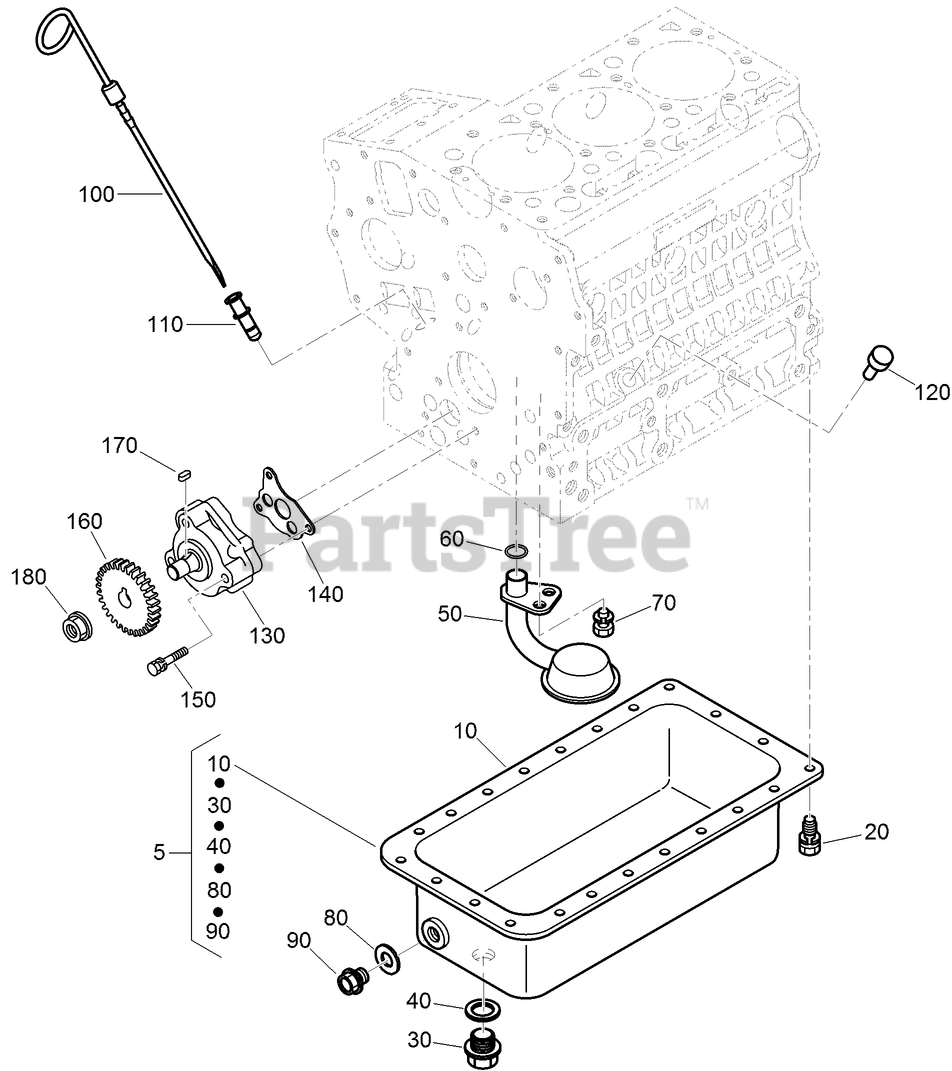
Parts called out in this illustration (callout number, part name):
5	OIL PAN KIT
10	PAN-OIL
30	PLUG-DRAIN
40	GASKET-PAN, OIL
50	STRAINER-PICKUP, OIL
60	O-RING
80	GASKET
90	PLUG-DRAIN
100	GAUGE-OIL
110	GUIDE-GAUGE, OIL
120	PLUG-GAUGE, OIL
130	OIL PUMP ASM
140	GASKET-PUMP, OIL
160	GEAR-DRIVE, OIL PUMP
170	KEY-FEATHER
180	NUT-FLANGE
